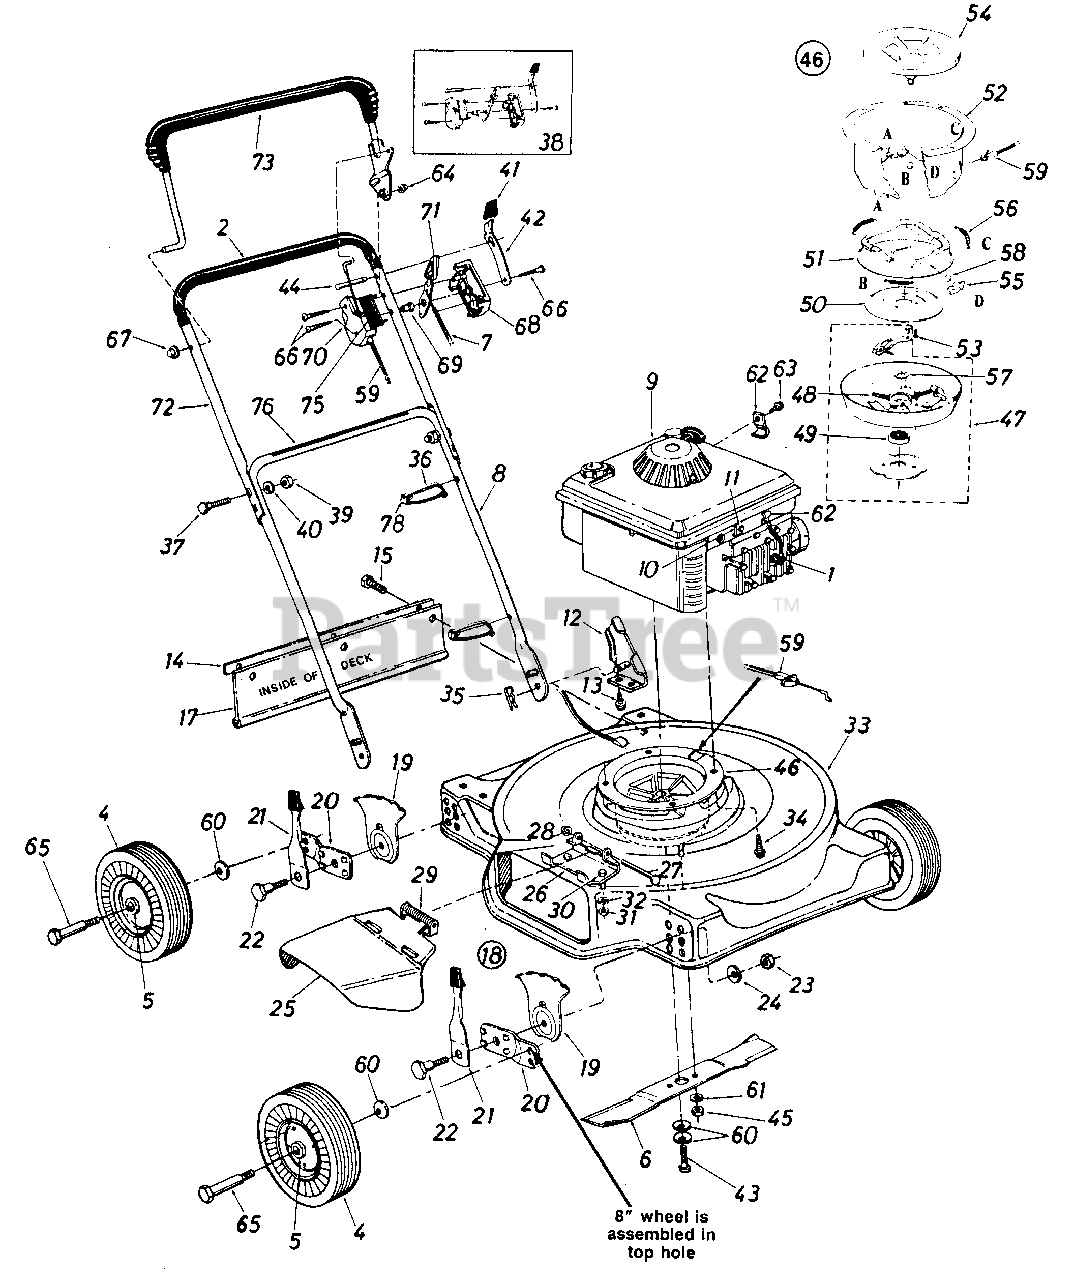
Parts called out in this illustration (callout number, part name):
1	INSULATOR-SPARK PLUG
2	GRIP-SHRINK-25 IN
4	WHEEL ASSY
5	BEARING-FORTIFLEX
6	BLADE-20IN
7	WIRE-THROTTLE
8	LOWER HANDLE
10	CLAMP-CASING
11	SCREW-HEX WASH HD TAP
12	BRACKET ASSY-HDLE
13	SCREW-HEX WASH HD 5/16-18X1/2
14	STRIP-RETAINING
15	SCREW-HEX WASH HD
17	FLAP-RR
18	ADJUSTER ASSY-HGT-RH
19	PLATE-HGT ADJ
20	BAR-PIVOT
21	LEVER & KNOB ASSY
22	SCREW-SHLD
23	NUT-HEX 3/8-16
24	WASHER-BELL .390 ID X 1.375 X .062
25	DEFLECTOR ASSY-CHUTE
26	PLATE-ADAPTER
27	PIN-PIVOT
29	SPRING-TORSION
30	SCREW-HEX 1/4-20 X .50
31	NUT-HEX 1/4-20
32	LOCK WASHER 1/4 DIA
33	DECK ASSEMBLY-20IN
34	SCREW-HEX HD TAP 1/4-20 X 7.5
35	PIN-INTERN COT-5/16 DIA
36	TIE-CABLE
37	BOLT-CARRIAGE-CURV 5/16-18 X 1.38
38	KIT-THROTTLE CONTROL
39	NUT-HEX 5/16-18
40	WASHER-LOCK-5/16
41	KNOB
42	SPRING-LOCKOUT
43	SCREW-HEX 3/8-24 X 2.00
44	PIN-LOCKING
45	NUT-HEX 3/8-24
46	CLUTCH ASSY-BLADE BRAKE-PUSH
47	HOUSING-CLUTCH BLADE
49	BEARING-BALL
50	CONE-CLUTCH
51	CONE-BRAKE CUP
52	HOUSING-CLUTCH
53	SCREW-HEX WASH 1/4-20X.75
54	ADAPTER-FAN
55	BALL-BLOCK
56	SPRING-EXTENSION
57	WASHER-FL .687 X 1.060 X .032
58	BALL-STEEL
59	CABLE-CLUTCH 43 IN
60	WASHER-BELL .400 ID X .88 X .060
61	WASHER-LOCK-3/8
62	CLAMP-CASING
63	SCREW-HEX B-TAP #10 X .38
65	SCREW-SHLD .498 DIA X 1.450
66	SCREW-TRUSS MACH
67	NUT-SPEED
68	PANEL HALF-CONTROL
69	PIN-CONTROL DISC
70	PANEL HALF-CLUTCH
71	LEVER-THROTTLE CONT-REV
72	HANDLE-UPPER
76	LABEL-BBC-INST
78	TIE-CABLE
